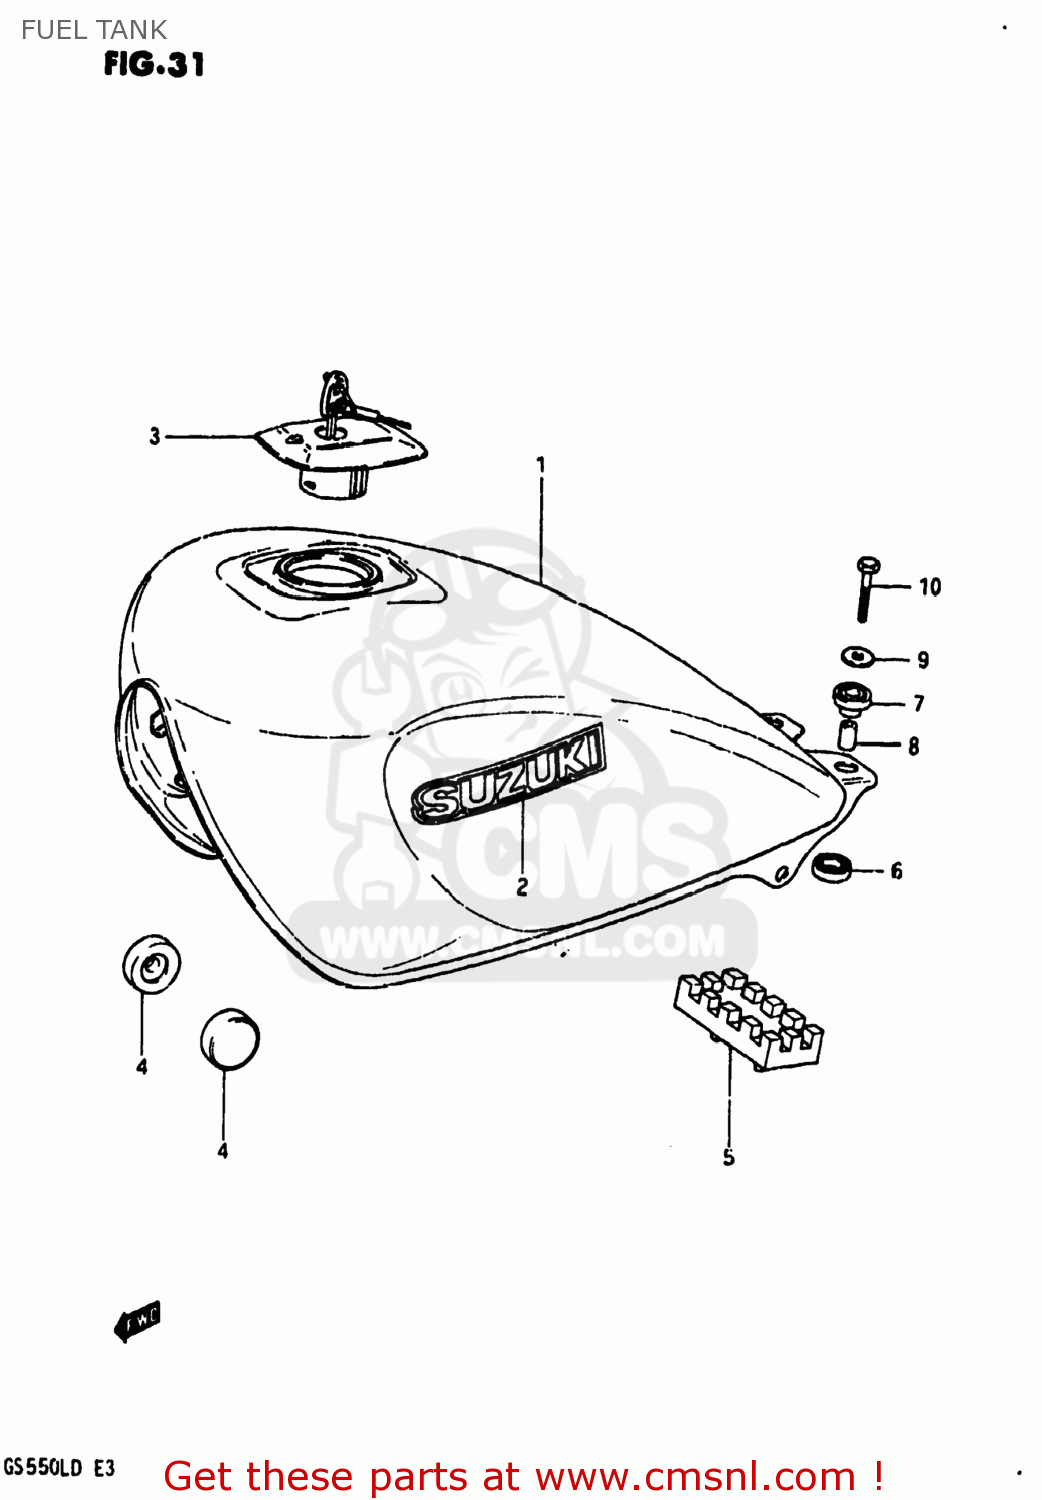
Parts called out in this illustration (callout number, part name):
1	TANK ASSEMBLY,FUEL
2	EMBLEM,FUEL TANK
3	CAP SET,FUEL TANK
4	CUSHION
5	CUSHION,FUEL TANK
6	CUSHION
7	CUSHION
8	SPACER
9	WASHER (6.5X24X1.6)
10	BOLT
